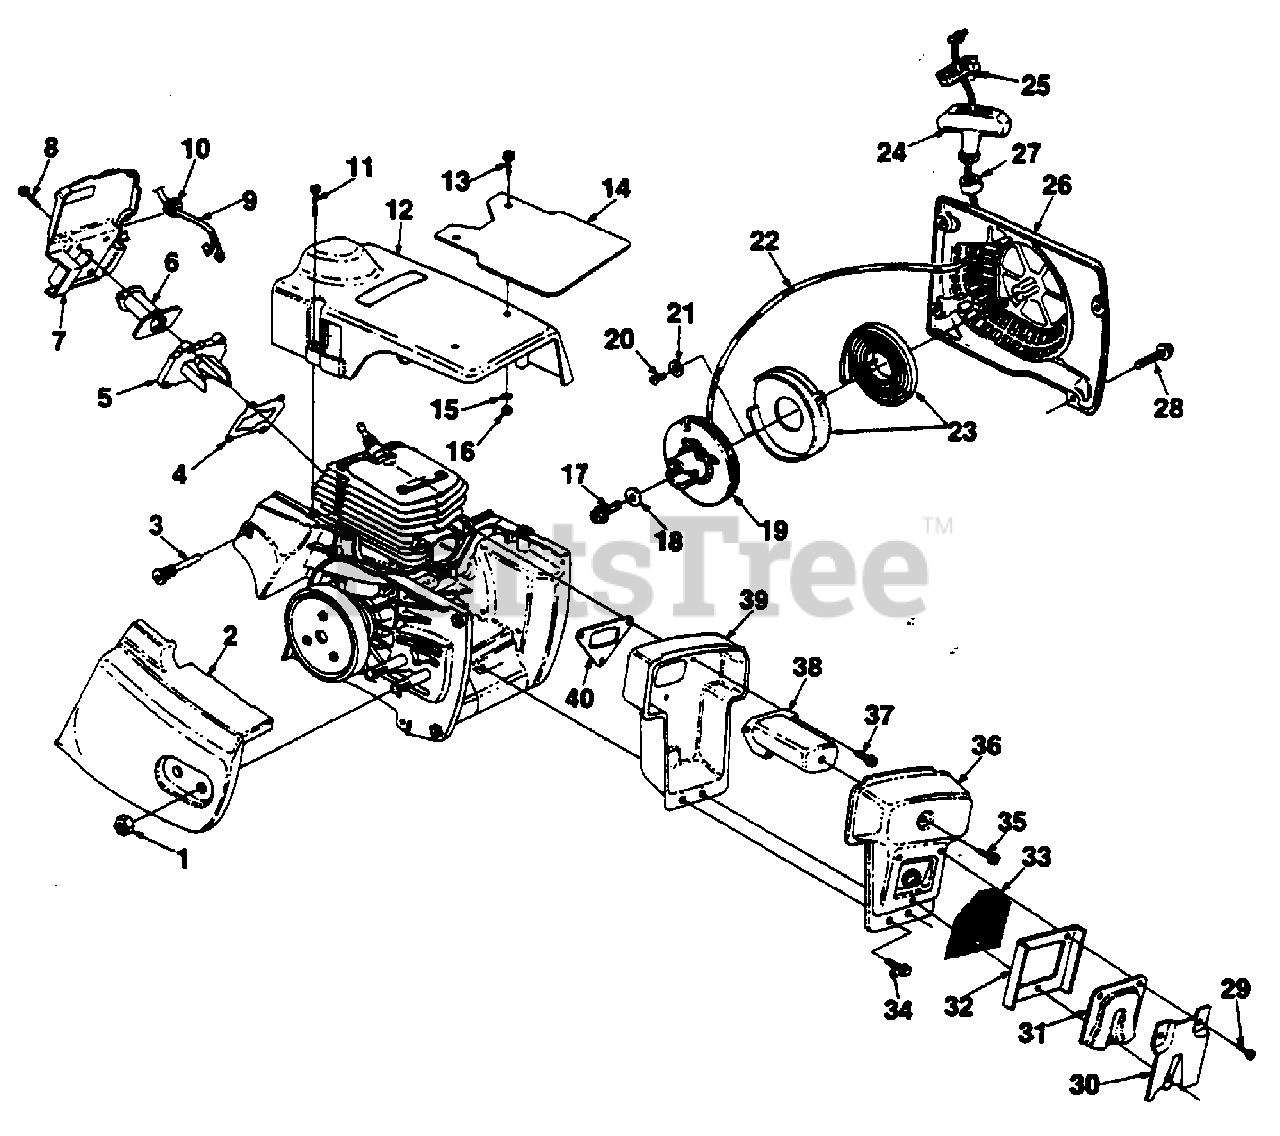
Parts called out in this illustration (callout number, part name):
1	NUT- (3/8-16 x 5/16")
2	COVER- Drivecase
3	PIN- Isolator
4	GASKET- Intake
5	ADAPTOR- Intake
6	BOOT
7	BAFFLE- Cylinder
8	SCREW- Mach. hex. (8-32 x 3/4")
9	LEAD- Ground
10	GROMMET
11	SCREW- Cylinder cover
12	COVER- Cylinder
13	SCREW- (#10 Pan hd.)
14	SHIELD- Heat
15	WASHER- Flat #10
16	NUT- Locking hex (10-24)
17	SCREW- Thread forming (#10 x 5/8")
18	WASHER- Retaining
19	CUP & PULLEY
20	SCREW- Plastite (6 x 3/8")
21	WASHER- Flat (#8)
22	ROPE- Starter
23	RETAINER & SPRING
24	GRIP- Starter
25	INSERT- Rope retaining
26	HOUSING- Starter
27	BUSHING
28	SCREW- Mach. (10-24 x 5/8")
29	SCREW- (8-32 x 1/2")
30	SHIELD- Muffler
31	CAP- Muffler
32	SUPPORT- Spark arrestor
33	SCREEN- Spark arrestor
34	SCREW
35	SCREW- Mach hd. (10-32 x 3/8")
36	COVER- Muffler
37	SCREW- Hex sems (#12)
38	DIFFUSER- Muffler
39	BODY- Muffler
40	GASKET- Muffler
